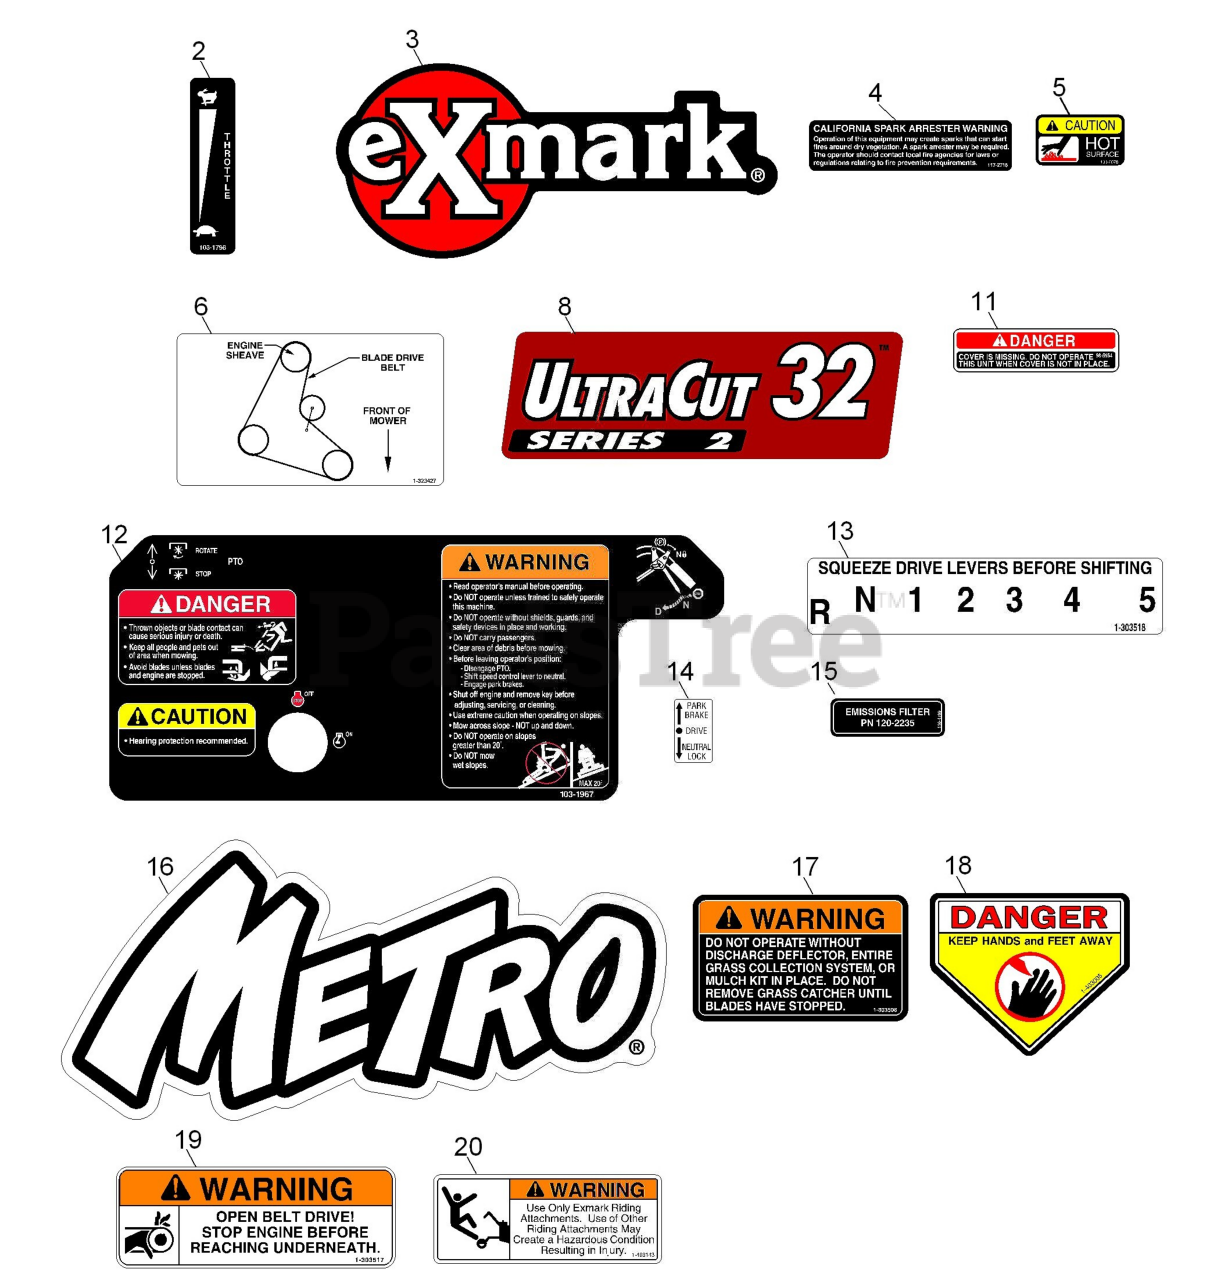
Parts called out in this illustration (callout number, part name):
2	DECAL,THROTTLE ONLY
3	DECAL,EXMARK LOGO
4	DECAL-ARRESTER, SPARK
5	DECAL-CAUTION
6	DECAL,BELT ROUTING 32/36
8	DECAL-ULTRACUT 32 SERIES
11	DECAL-COVER, MISSING
12	DECAL,CONSOLE
13	DECAL,SHIFTER
14	DECAL,NEUTRAL/BRAKE
15	DECAL-FILTER, EMISSIONS
16	DECAL,METRO MODEL
17	DECAL-WARNING, DISCHARGE
18	DECAL-DANGER
19	DECAL,BELT DRIVE
20	DECAL,SULKY WARNING
